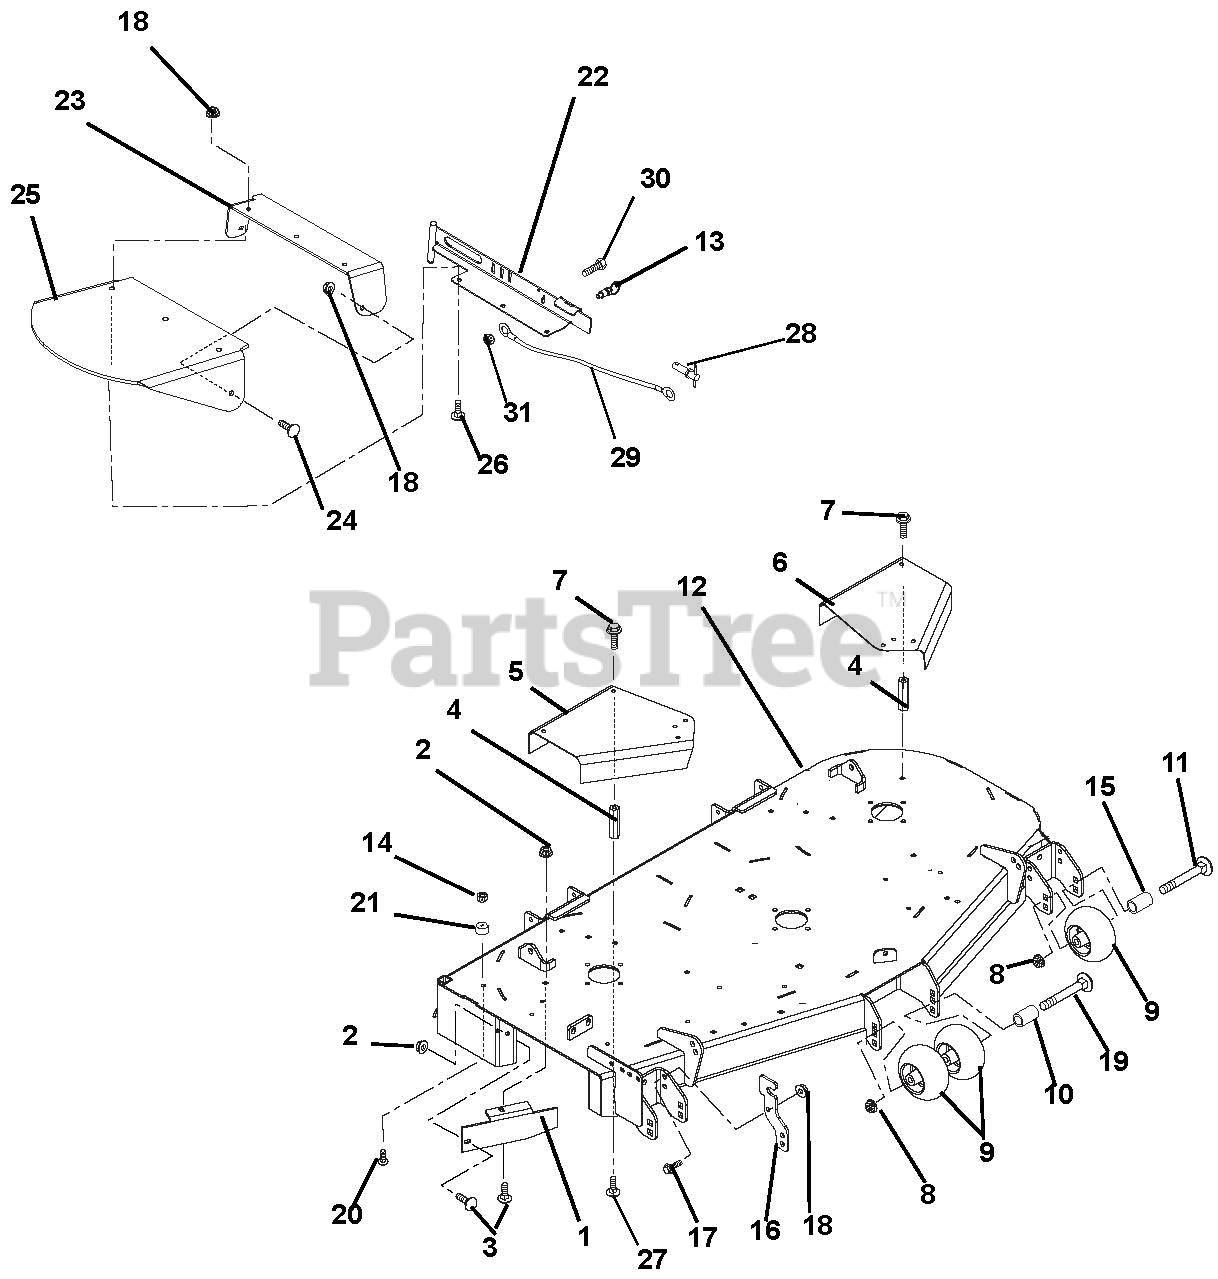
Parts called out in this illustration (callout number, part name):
1	52-in. Discharge Baffle
1	60-in. Discharge Baffle
1	66-in. Discharge Baffle
1	72-in. Discharge Baffle
2	Nut, .31-18 Nyloc Flange
3	Bolt, Round Head Square Neck .31-18 x 1.00 Grade 5
4	Nut, Coupling .31-18 x 3.00
5	52-in. Right Hand Spindle Guard
5	60-in. Right Hand Spindle Guard
5	66/72-in. Right Hand Spindle Guard
6	52-in. Left Hand Spindle Guard
6	60-in. Left Hand Spindle Guard
6	66/72-in. Left Hand Spindle Guard
7	Bolt, SEMS .31-18 x .62
8	Nut .50-13 Nyloc Flange
9	Anti-Scalp Wheel
11	Bolt-Round Head Square Neck .50-13 x 5.00
12	52-in. Mower Deck
12	60-in. Mower Deck
12	66-in. Mower Deck
12	72-in. Mower Deck
13	Pin, Plunger Pull .50-13 Thread x .310 Diameter
14	Nut, Locking, Center .31-18
15	Spacer, .510 x .625 x 3.35
16	Chute, Storage Bracket
17	Bolt, Hex .38-16 x 1.00
18	Nut, .38-16 Nyloc Flange
19	Bolt, Round Head Square Neck .50-13 x 8.50
20	Bolt, Round Head Square Neck .31-18 x 1.50
21	Bumper, Recessed 1.50 x .63 , .31 Thru Hole
22	52-inch and 60-inch Discharge Chute Mounting Weldment
22	66/72-inch Discharge Chute Mounting Weldment
23	Rubber Discharge Chute Support
24	Bolt, Round Head Square Neck .38-16 x 1.00 Grade 5
25	Chute, Rubber Discharge
26	Bolt, Round Head Square Neck .38-16 x 1.25 Grade 5
27	Bolt, Round Head Square Neck .31-18 x .75
28	Pin, Spring Ball .375OD x 1.50
29	Cable, 6.0 LANYARD, Nylon
30	Bolt, Hex .25-20 x .75 Grade 5
31	Nut, Locking-Top-Flange .25-20
